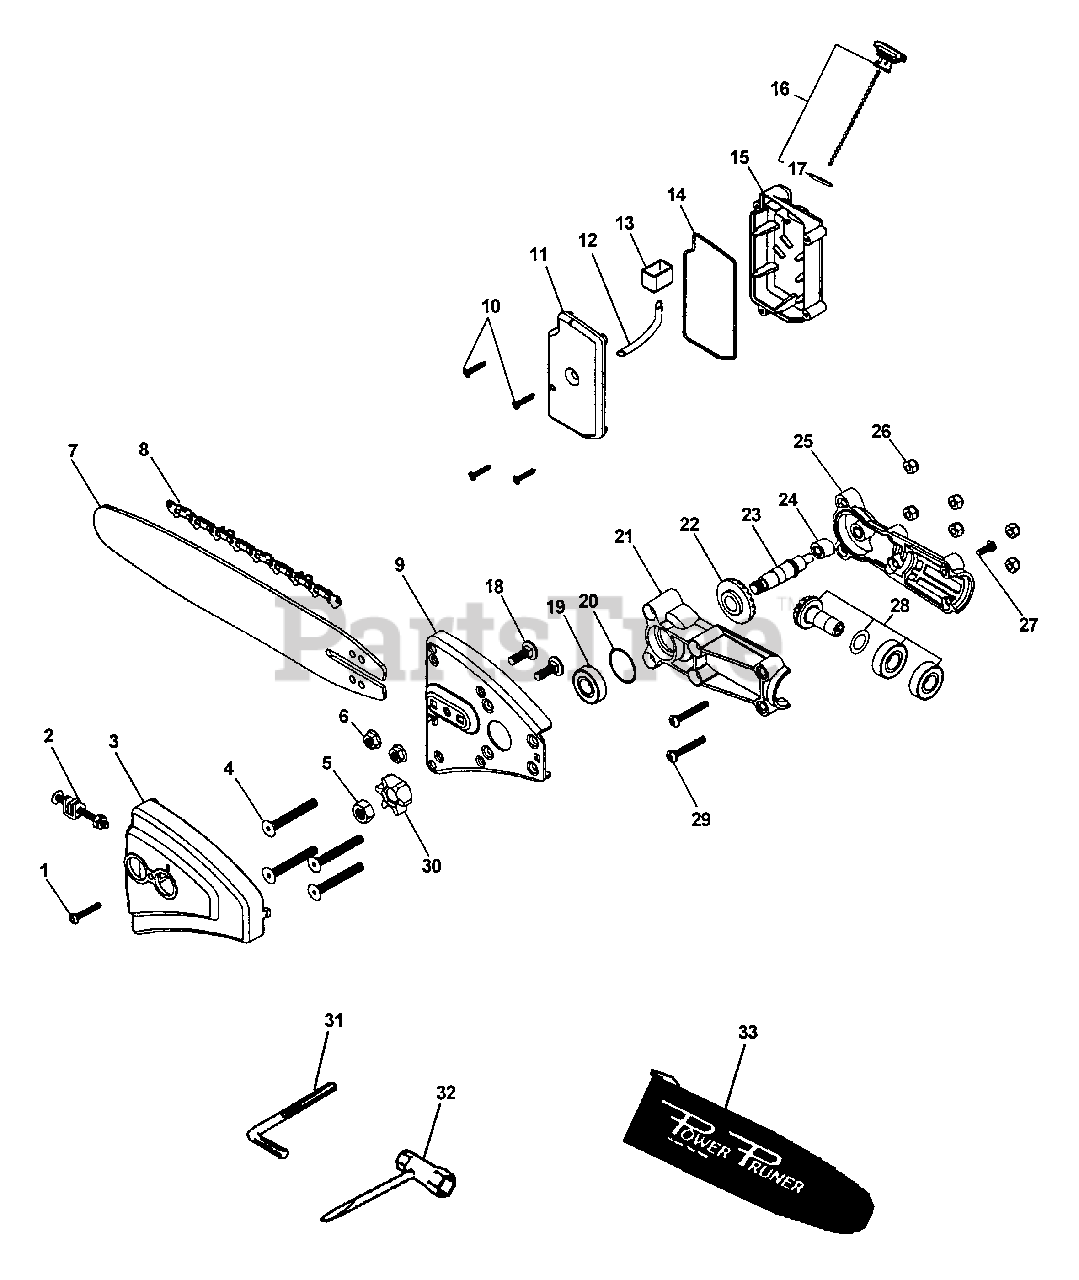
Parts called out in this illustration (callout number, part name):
1	SCREW - 8-32 X 1"
2	TENSIONER KIT
3	GUARD, SPROCKET
6	NUT - FLANGE
7	GUIDE BAR - 10" (25cm)
8	SAW CHAIN - 10" (25cm)
9	SAW BAR CARRIER
10	SCREW
11	TANK, OIL (CHAIN SIDE)
12	PIPE - 3X5X70 -- BLACK
13	CUP, OIL
15	TANK, OIL (CAP SIDE)
16	CAP ASSY
18	BOLT
19	BEARING, BALL - 6001 DDU
20	SHIM .004"
21	CASE, GEAR - RIGHT
22	GEAR - BEVEL
23	SHAFT GEAR ASSY
24	GUIDE, DRIVESHAFT
25	CASE, GEAR - RIGHT
26	LOCKNUT - 10-24
27	SCREW
28	SHAFT GEAR ASSY
29	SCREW - 10-24 X 1-1/4"
30	SPROCKET
31	HEX KEY
32	T-WRENCH
33	COVER, GUIDE BAR
